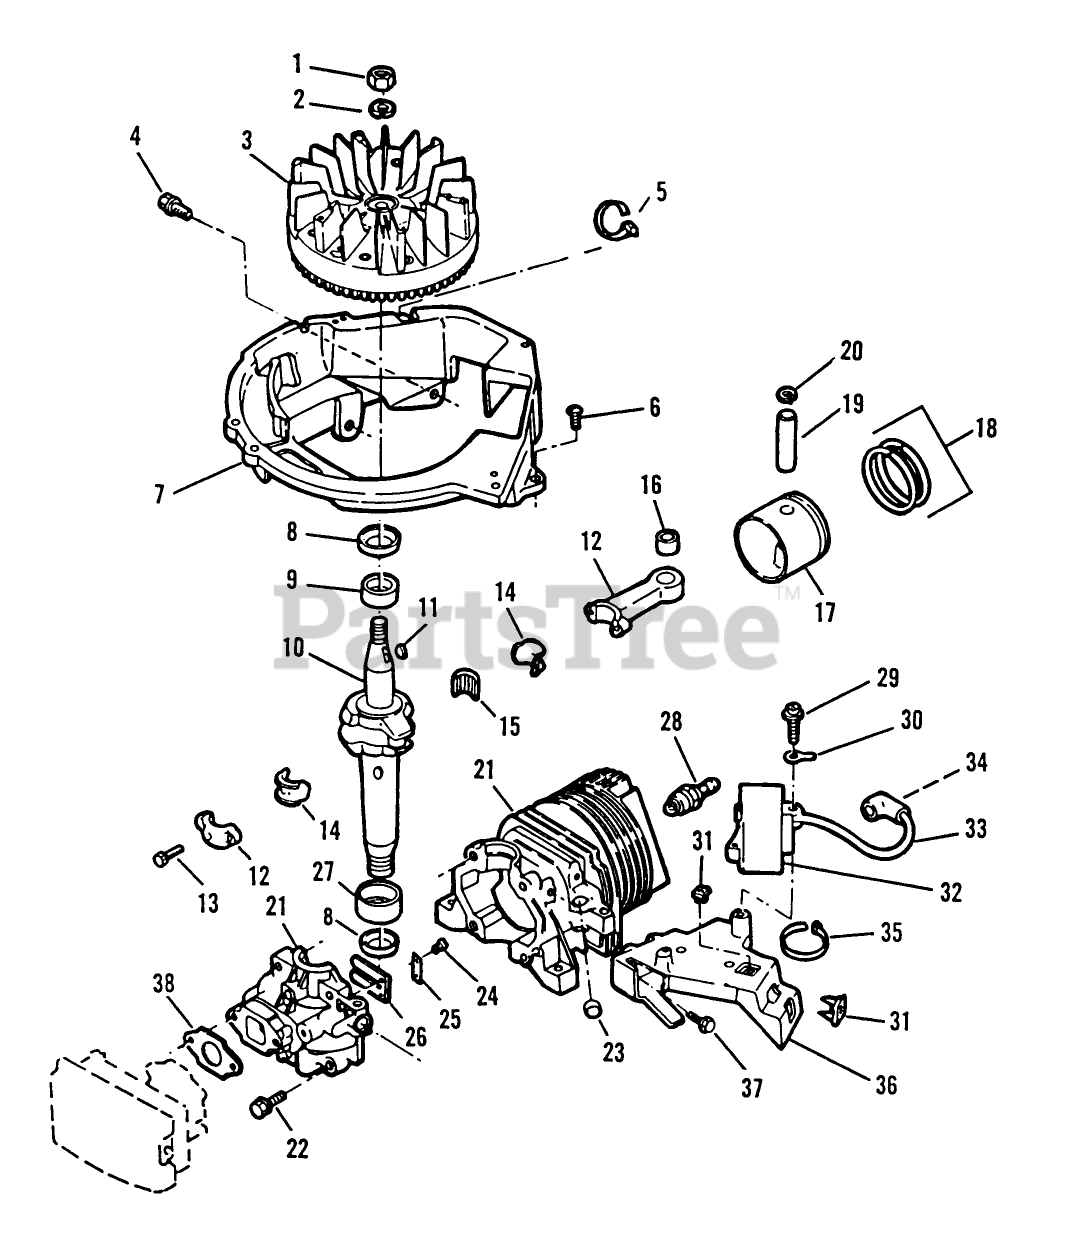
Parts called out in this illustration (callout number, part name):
1	NUT
4	SCREW-SEMS
6	SCREW F
8	SEAL-OIL
9	BEARING V
11	KEY
13	SCREW-HSH
14	LINER ASM
15	BEARING-NEEDLE
16	BEARING AY F
20	RING-RETAINING
22	SCREW-H.W.HD. F
23	PLUG-CORE VF
24	SCREW-HH
25	PLATE-BACKUP, REED
27	BEARING V
30	TERMINAL S
31	NUT-CLIP
33	HT LEAD&COVER XEV
36	C.D. BRKT F
38	GASKET CARB S
